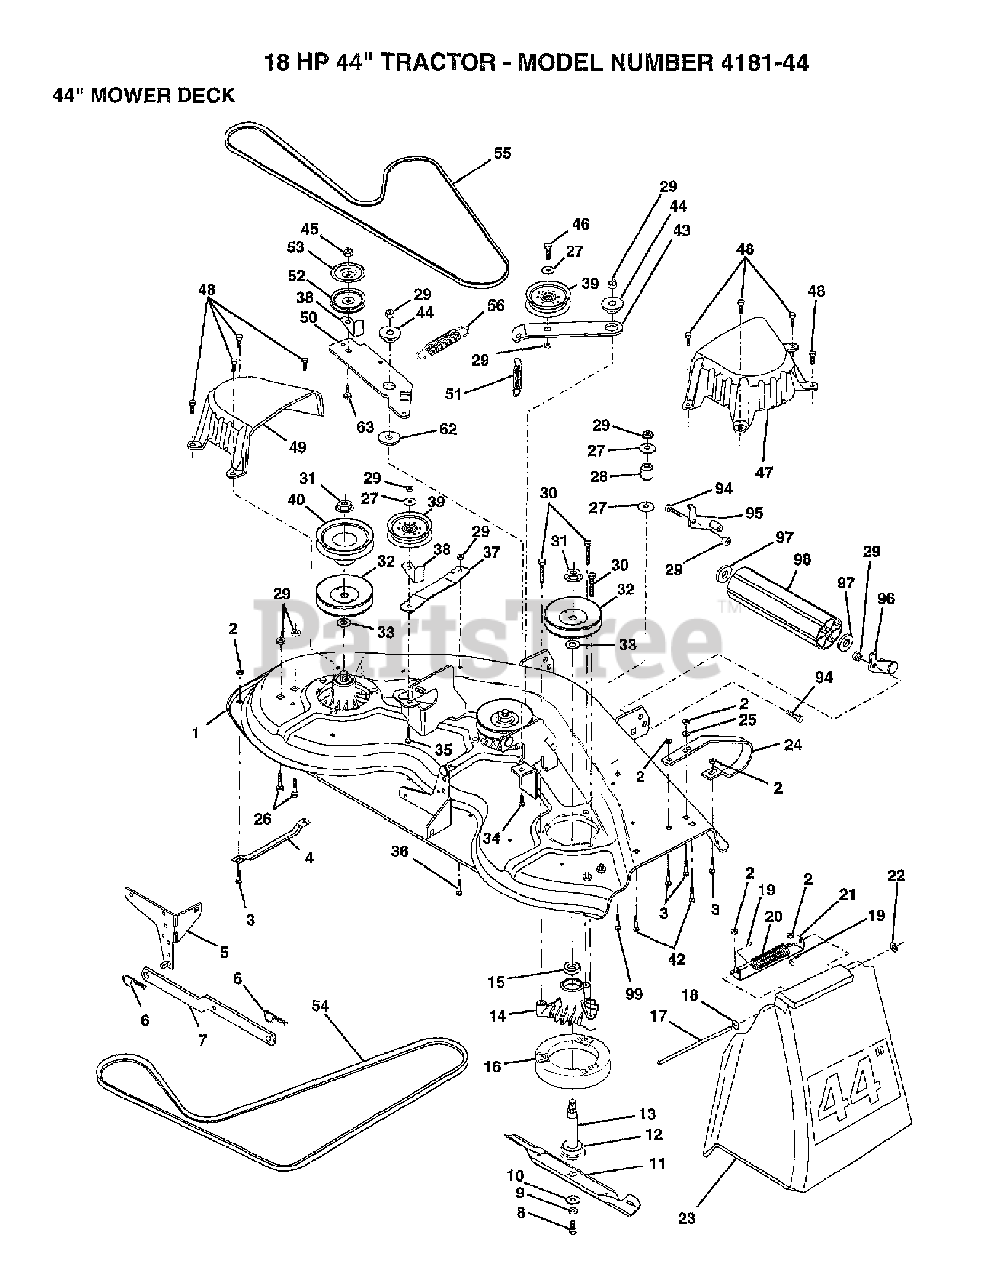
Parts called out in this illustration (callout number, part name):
2	NUT.71038.31-18.HEX.NYLOCK
3	BOLT.5/16-18.
4	RUNNER LH
5	BRACKET SWAY BAR
6	RETAINER SPRING
8	BLADE BOLT
10	WASHER.BLADE
11	44" BLADE-HI PERFORMANCE
12	BEARING.BALL.#6204.(MANDREL)
13	SHAFT.ASM.W/BEARING
14	HOUSING.MANDREL
17	ROD-HINGE T
18	WASHER
19	CAP-SLEEVE LT
20	DEFLECTOR SPRG T
21	BRACKET, DEFLECTOR
22	NUT PUSH M
23	DEFLECTOR SHIELD
24	RUNNER-RH YTV
25	WASHER M
28	IDLER SPRING SPACER
29	NUT
30	Hex Washer Head Bolt, .313-18 X 1.19
33	WASHER
35	BOLT
37	STIFFENER ARM
39	IDLER-FLAT GT
40	PULLEY.DRIVEN.44"
42	BOLT
43	ARM.IDLER.SEC.44"
45	LOCKNUT
46	BOLT
47	COVER MANDRELL
48	SCREW.1/4-20X5/8
49	COVER.MANDREL.LH.44"
50	ARM.IDLER.PRIMARY
51	SPRING.SEC.44"VEN
52	PULLEY IDLER
53	SHIELD IDLER
55	BELT
63	BOLT.3/8-16X1.50
94	BOLT
95	Roller Bracket Assembly, LH
98	MANUAL, OPERATOR
99	BOLT
